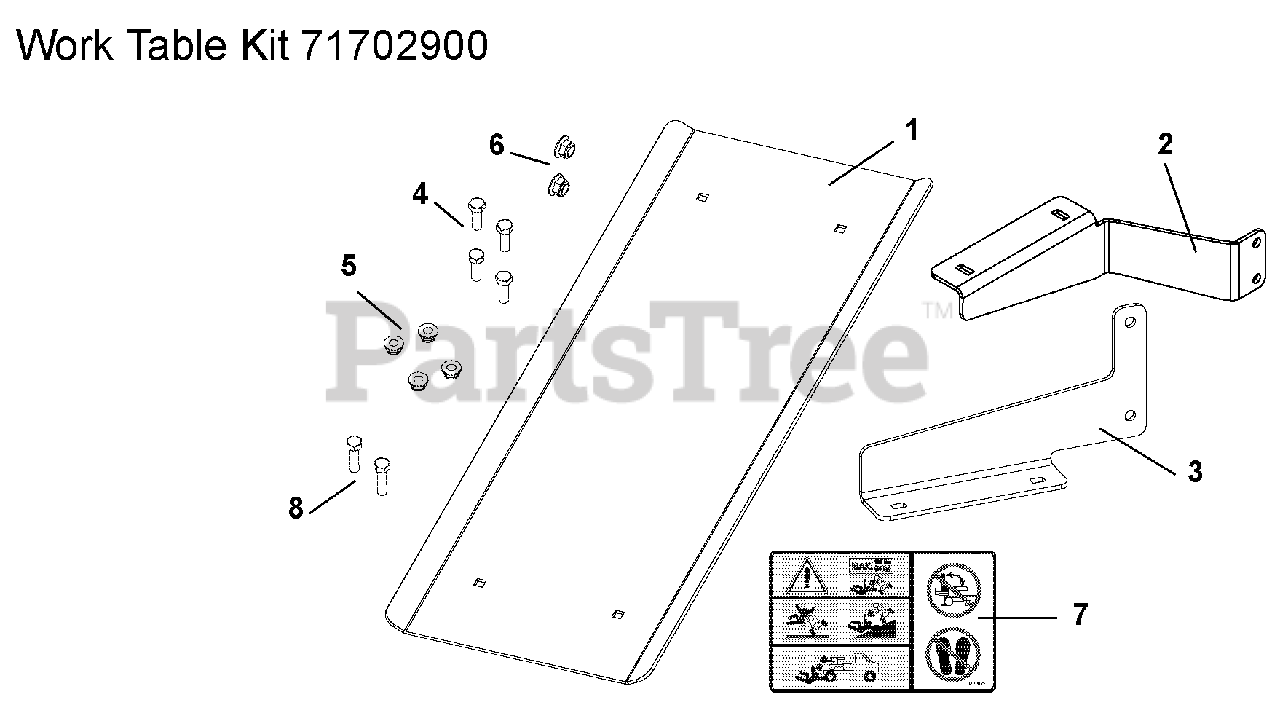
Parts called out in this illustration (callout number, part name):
1	TABLE, WORK - LOG SPLITTER
2	BRKT, REAR - WORK TABLE
3	BRKT, FRONT - WORK TABLE
4	@BLT-RHDSSQNK .31-18X1.00 G5YZ
5	@NUT-LK-NYL-FLG .31-18 YWZC
6	@NUT-LK-TOP-FLG .38-16 YWZC
7	DECAL,SPLITTER TABLE
8	@BLT-HEX .38-16X1.00 GR5 YWZC
